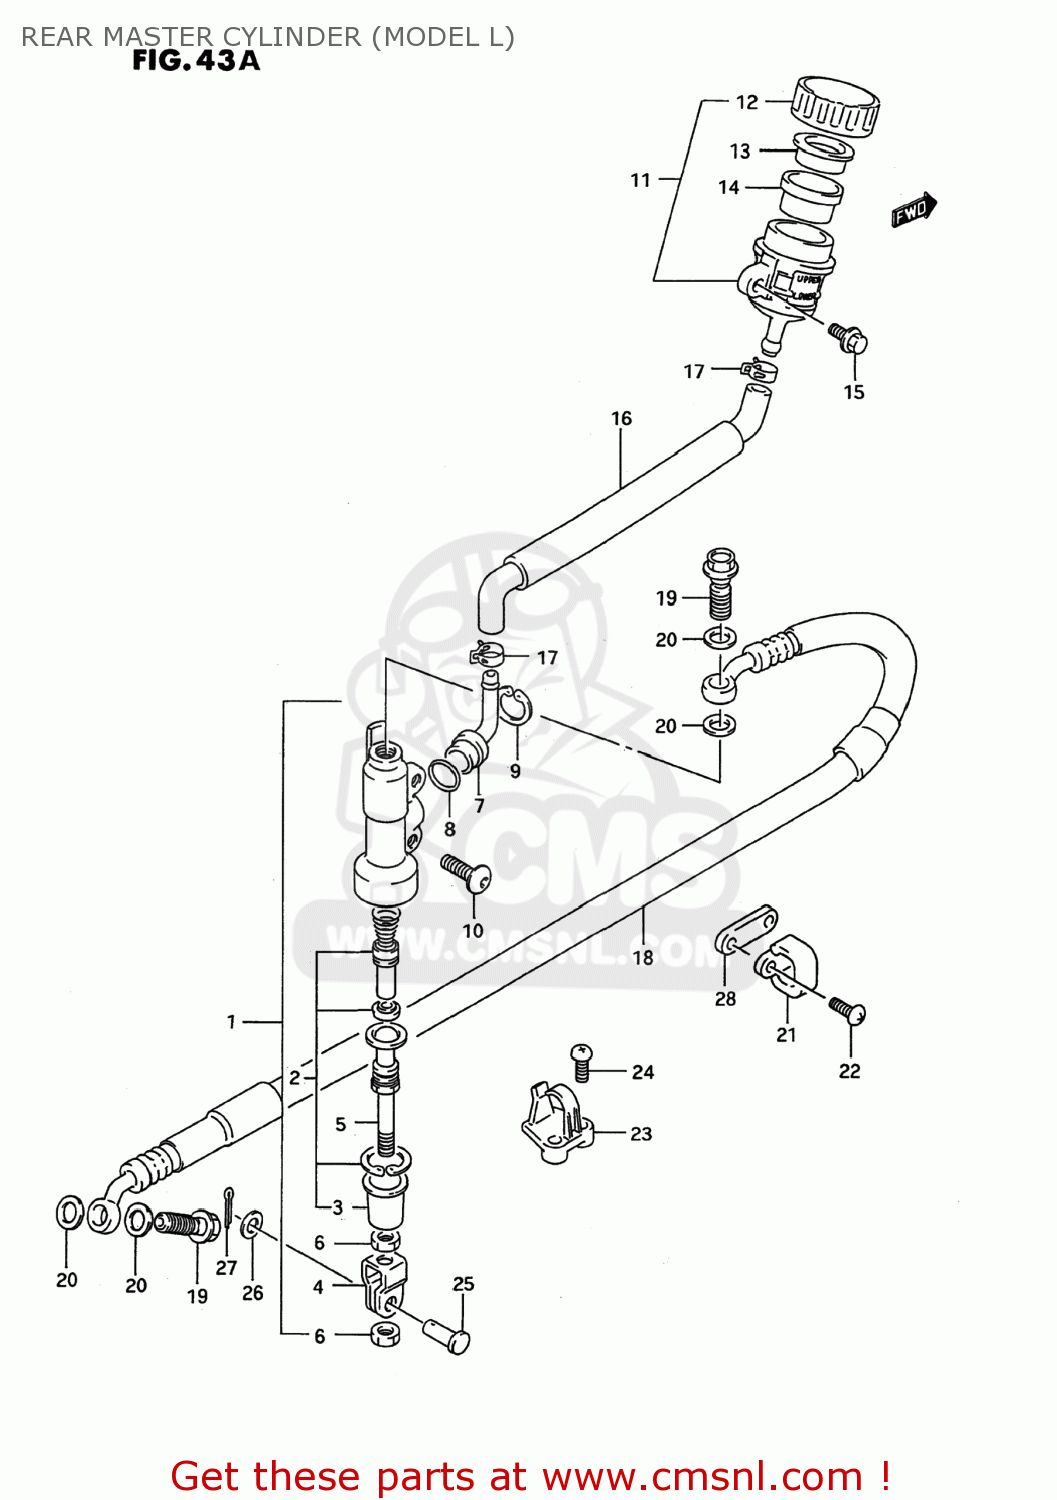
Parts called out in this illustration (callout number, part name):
1	CYLINDER ASSEMBLY,REAR MASTER
2	PISTON/CUP SET
3	BOOT
4	YOKE
5	ROD,PUSH
6	NUT
7	CONNECTOR
8	O RING
9	CIRCLIP
10	SCREW
11	TANK ASSY,RESERVOIR
12	CAP
13	PLATE
14	DIAPHRAGM
15	BOLT
16	HOSE,RESERVOIR
17	CLAMP,RESERVOIR HOSE
18	HOSE,RR BRAKE
19	BOLT UNION
20	WASHER(10X15X1.5)
21	GUIDE,RR BRAKE HOSE
22	SCREW
23	GUIDE,RR BRAKE HOSE
24	SCREW
25	PIN(8X20)
26	WASHER(8.5X13X1.6)
27	PIN
28	SEAT,RR BRAKE HOSE GUIDE
